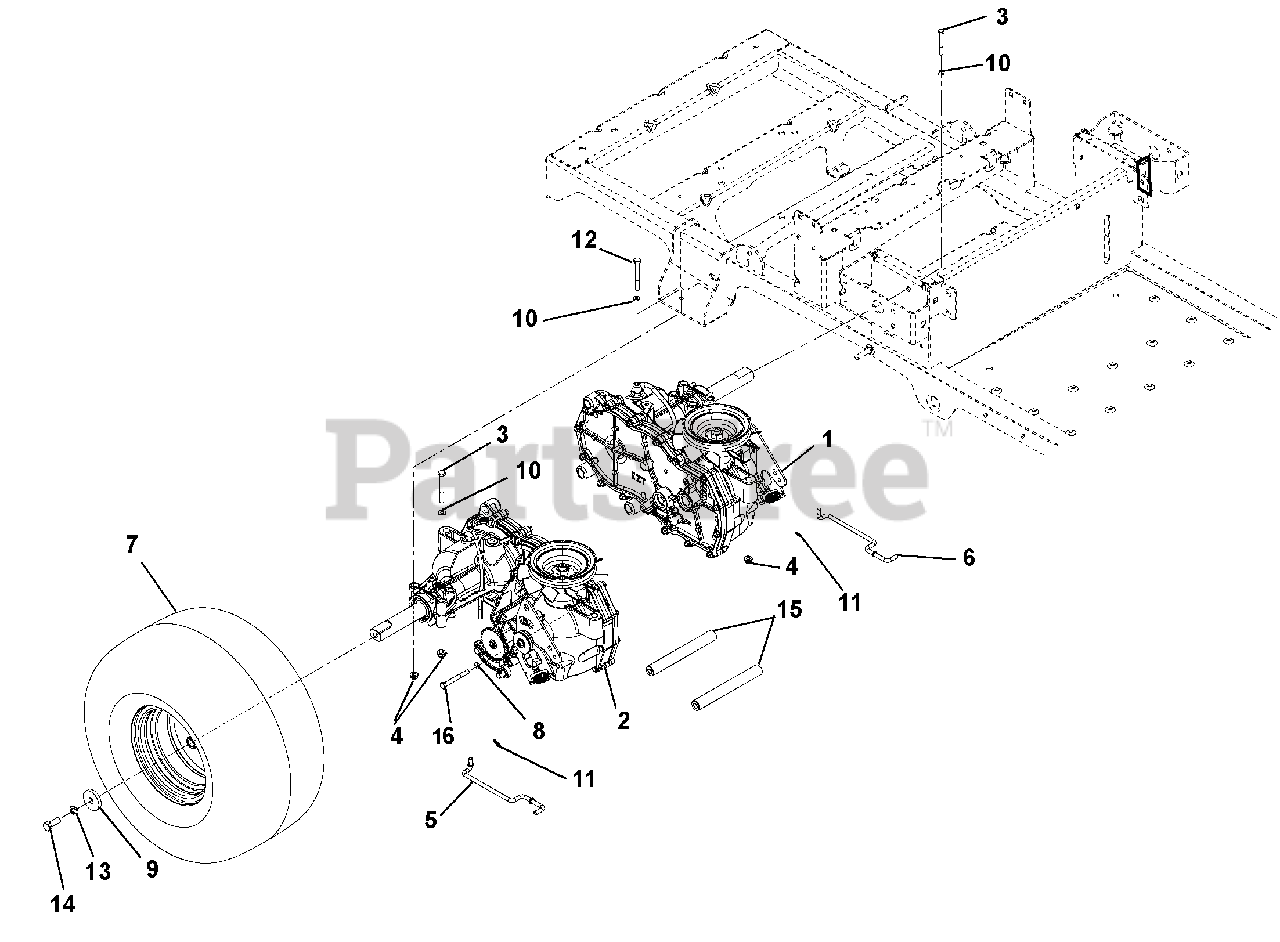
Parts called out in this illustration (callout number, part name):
1	TRANSAXLE, LH EZT D-SHAFT
2	TRANSAXLE, RH EZT D-SHAFT
3	@BLT-HEX .31-18X2.25 GR5 YWZC
4	@NUT-LK-NYL-FLG .31-18 YWZC
5	DUMPVALVE, RH LCZ
6	DUMPVALVE, LH LCZ
7	TIRE-ASM 18X6.5-8 4 PLY DSHAFT
8	WSHR-FL-STL .406X1.00X.188 YWZ
9	WSHR,FLT STL.406X1.50X.245YWZC
10	@WSHR-FL-STL.38X.875X.083 YWZC
11	PIN-HAIR INT .06X.18X.77
12	@BLT-HEX .31-18X2.75 GR5 YWZC
13	@WSHR-LK .38X.094 REG YWZC
14	BLT-HEX .38-16X1.0 GR8 YZ EP30
15	SHAFT, TRANSAXLE BRACE
16	@BLT-HEX .38-16X2.50 GR5 YWZC
